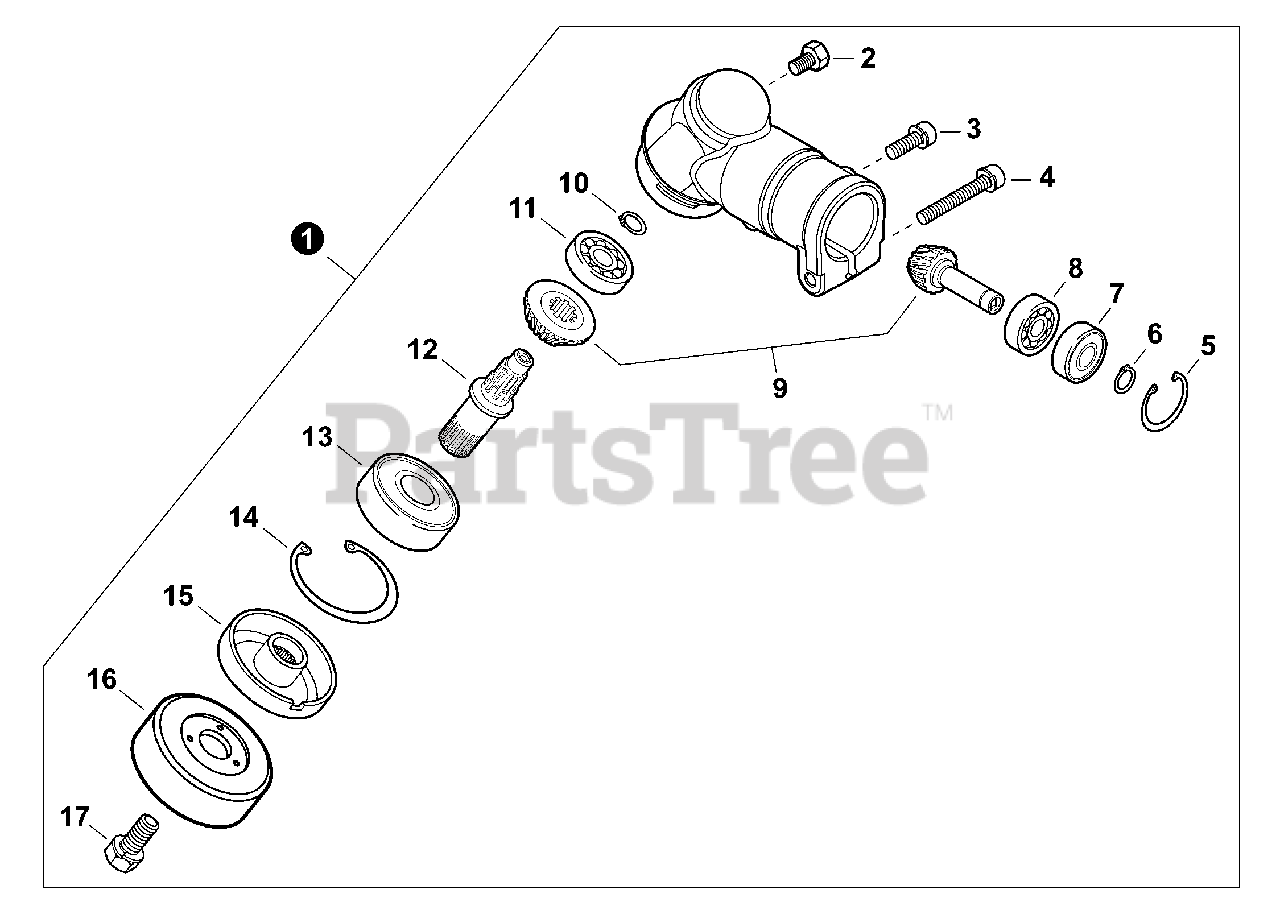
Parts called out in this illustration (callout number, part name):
1	GEAR CASE ASSY
2	BOLT M8×8
3	SCREW 5×12
4	BOLT M5×35
5	RING, SNAP 24
6	RING, SNAP Ø9
7	BEARING, BALL 609
8	BEARING, BALL 609
9	GEAR SET
10	RING, SNAP Ø6
11	BEARING, BALL 626 DDU
12	SHAFT, GEAR
13	BEARING, BALL 6000DDU
14	RING, SNAP 26
15	PLATE, ADAPTOR - UPPER
16	GUARD, BOLT
17	BOLT M7×1.0
